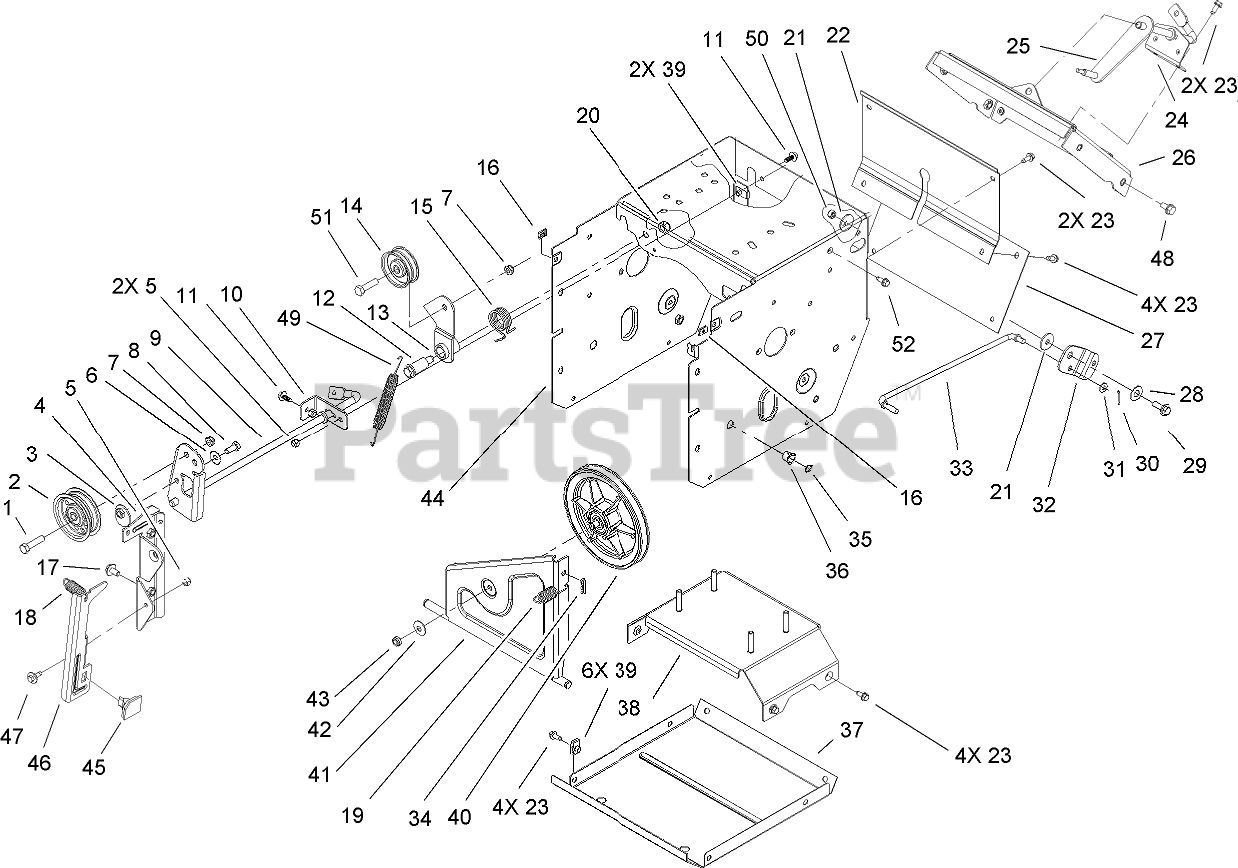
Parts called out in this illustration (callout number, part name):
1	SCREW-HH
2	PULLEY-IDLER
4	BRACKET-IDLER, IMPELLER
5	NUT-LOCK, NI
6	WASHER-BELLEVILLE
7	NUT-LOCK, NI
8	SCREW-HH
9	IMPELLER CLUTCH ASM
10	BRACKET-REAR, CLUTCH
11	SCREW-HHF
12	BOLT-SHOULDER
13	ARM-IDLER, TRACTION
14	PULLEY-IDLER
15	SPRING-TORSION
16	NUT-SPEED, U-TYPE
17	SCREW-HHF
18	SPRING-EXTENSION
19	SPRING-EXTENSION
20	NUT-LOCK, NI
21	WASHER-PIVOT
22	COVER-UPPER
23	SCREW-HWH
24	BRACKET-ROD, SHIFT
25	LEVER-CONTROL, TRACTION
26	SHIFT PLATE ASM
27	COVER-LOWER
28	WASHER
29	SCREW-SHOULDER
30	PIN-COTTER
31	WASHER-PLAIN
32	BELLCRANK-DRIVE
33	LINK-CONTROL, SPEED
34	PIN-COTTER
35	RING-RETAINING
36	BUSHING-NYLINER
37	PAN-BOTTOM
38	FRAME BRACE ASM
40	PULLEY-TRACTION
41	BRACKET-WHEEL, FRICTION
42	WASHER-BELLEVILLE
43	NUT-HEX
44	TRACTION FRAME ASM
45	PAD-BRAKE
46	ARM-BRAKE
47	SCREW-SHOULDER
48	SCREW-HWHTF
49	SPRING-EXTENSION
50	NUT-LOCK, NI
51	SCREW-HH
52	SCREW-HWH
